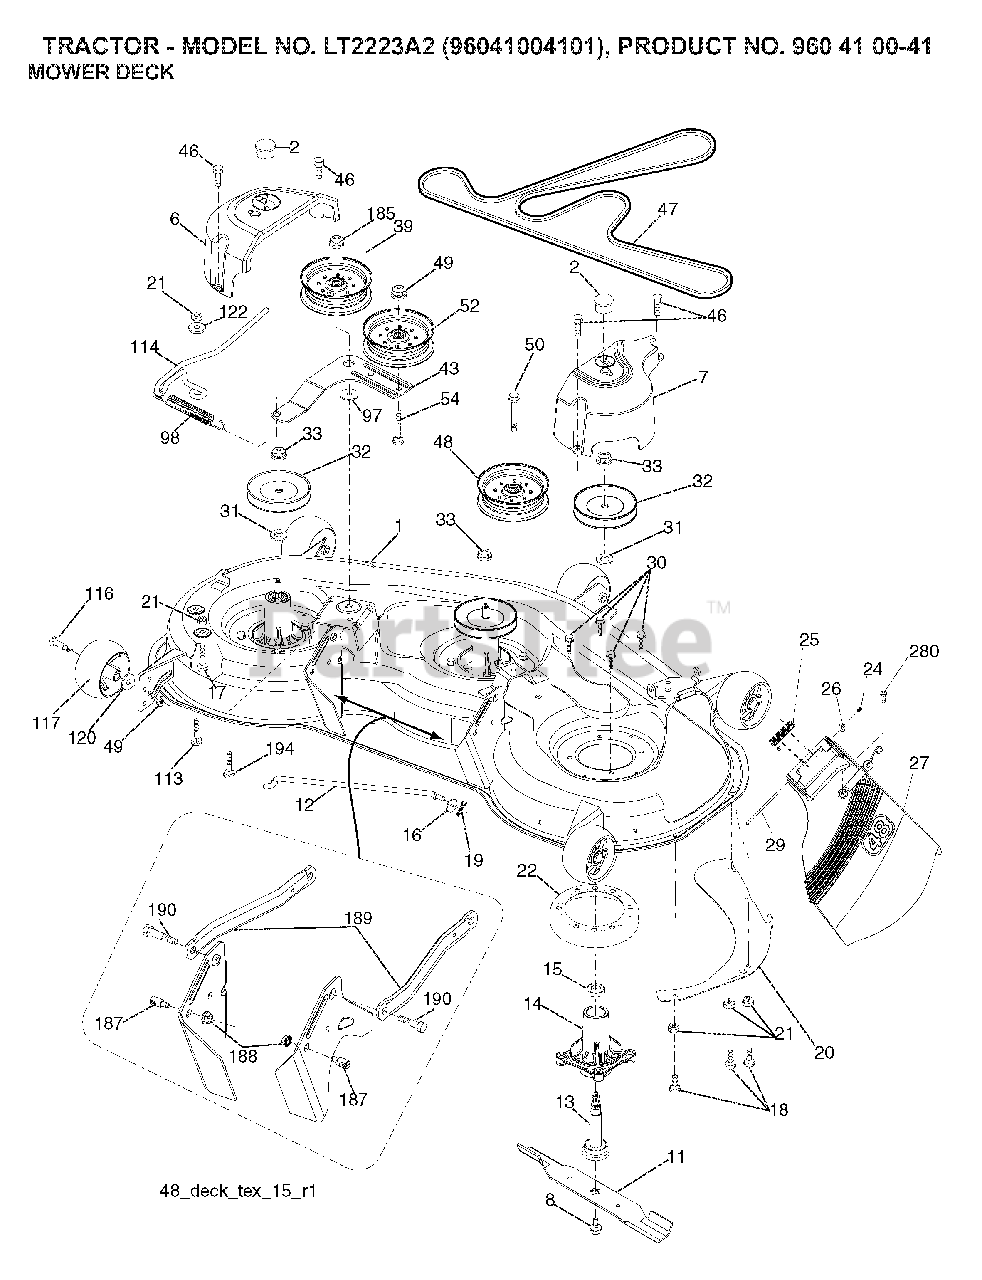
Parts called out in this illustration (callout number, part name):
1	DECK WELDMENT
8	BOLT 7/16 ASM BLADE
11	48" HI-LIFT BLADE
12	ROD.ANTI.SWAY.48/54"TE
13	SHAFT ASM MANDREL
14	HOUSING MANDREL
16	WASHER
17	BOLT
18	BOLT
19	PIN.COTTER.5/16.BOW TI
20	BAFFLE, VORTEX MWR
21	LOCKNUT
22	STRIPPER, MWR ROUND
24	CAP-SLEEVE LT
25	SPRING, TORSION
26	NUT PUSH M
29	ROD.HINGE
30	SCREW, WASHER HEAD
31	WASHER.SPACER.MANDREL
32	PULLEY MANDREL
33	NUT.FLANGE.LOCK.TOP
39	PULLEY.IDLER.4.50/HUB SPECIAL
43	ARM.IDLER
46	SCREW.1/4-20X5/8
47	BELT.DRIVE.DECK
48	PULLEY.IDLER.48"PRIMARY
49	NUT LOCK FLG 3/8-16 UNC
50	BOLT.3/8-16X1.50
52	PULLEY.IDLER.2006
54	SCREW TT 3/8-16X2-1/4 UNC
98	SPRING, DECK DRIVE
113	BOLT CRT
114	ROD.TENSION.RELIEF.TEX
116	BOLT.SHOULDER.3/8-16X3-5/8
117	WHEEL. GUAGE RALLY
122	BUSHING.RELIEF.TENSION
185	NUT.LOCK.FLANGE.7/16
187	STUD.FASTNER.W/ANTI-ROTATE
188	NUT LOCK HEX FLANGE 5/16-18
189	ARM.SUSPENSION.MOWER
190	BOLT.SHOULDER
194	BOLT.CARR.SQNK.7/16
280	SCREW 3/8-16X1/2
